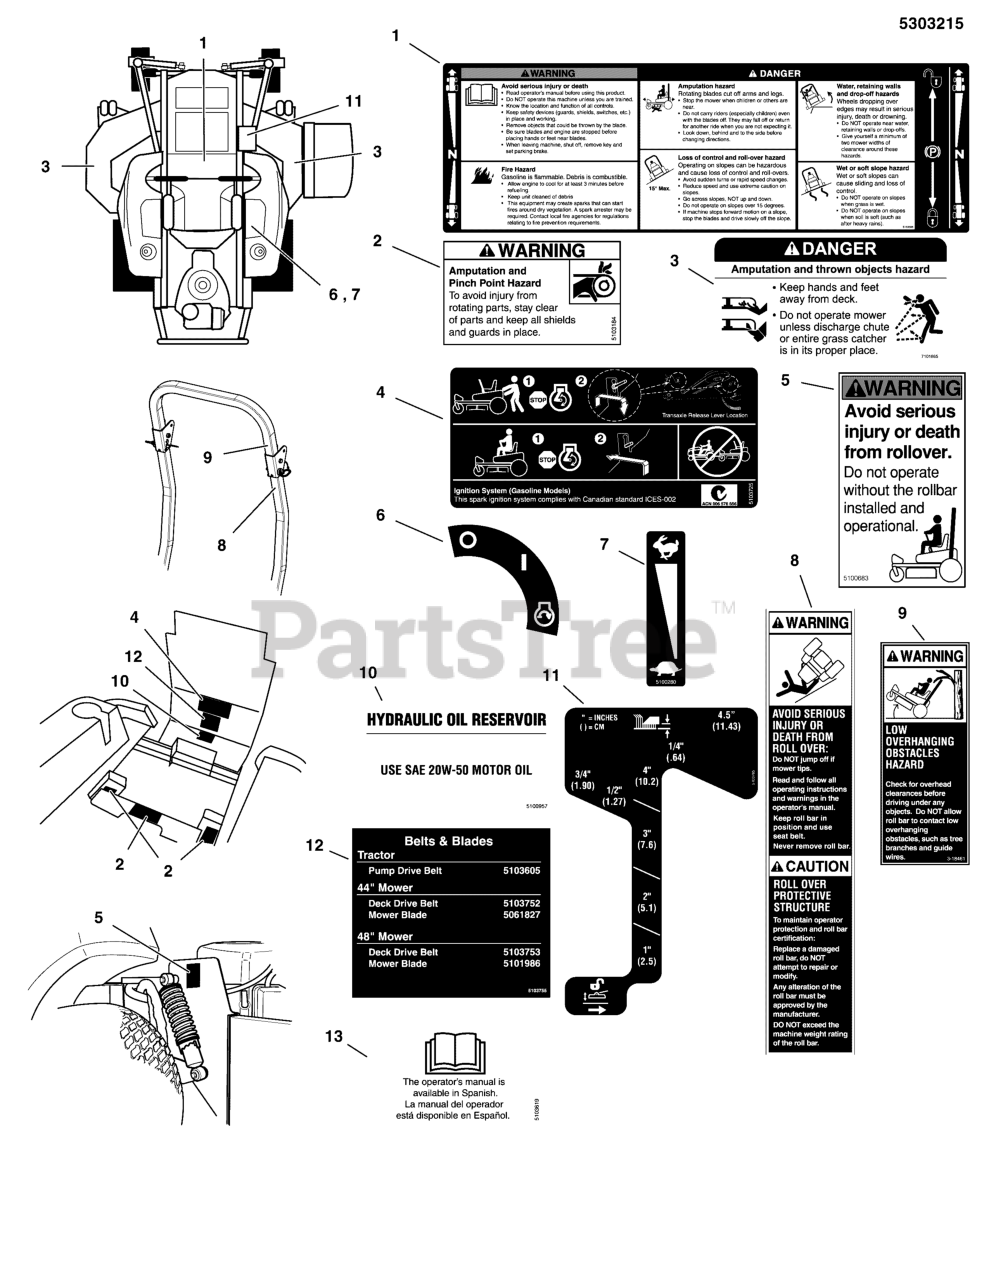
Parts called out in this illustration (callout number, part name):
1	DECAL, MAIN SAFETY
2	DECAL, WARNING, HAND IN BELT, ENG ONLY
3	DECAL, DANGER DO NOT OPERATE W/O DEFLECT
4	DECAL, TRANSAXLE RELEASE, 600/700
5	DECAL, WARNING, ROLL BAR
6	DECAL, IGNITION SWITCH
7	DECAL, THROTTLE CONTROL
8	DECAL, WARNING & CAUTION, ROPS
9	DECAL, WARNING OVERHANG, ROPS
10	DECAL, HYDRAULIC OIL, SAE 20W50
11	DECAL, CUT HEIGHT, 600
12	DECAL, BELT & BLADE, IS600Z/ZTS600
13	DECAL, MANUAL AVAIL IN SPANISH
